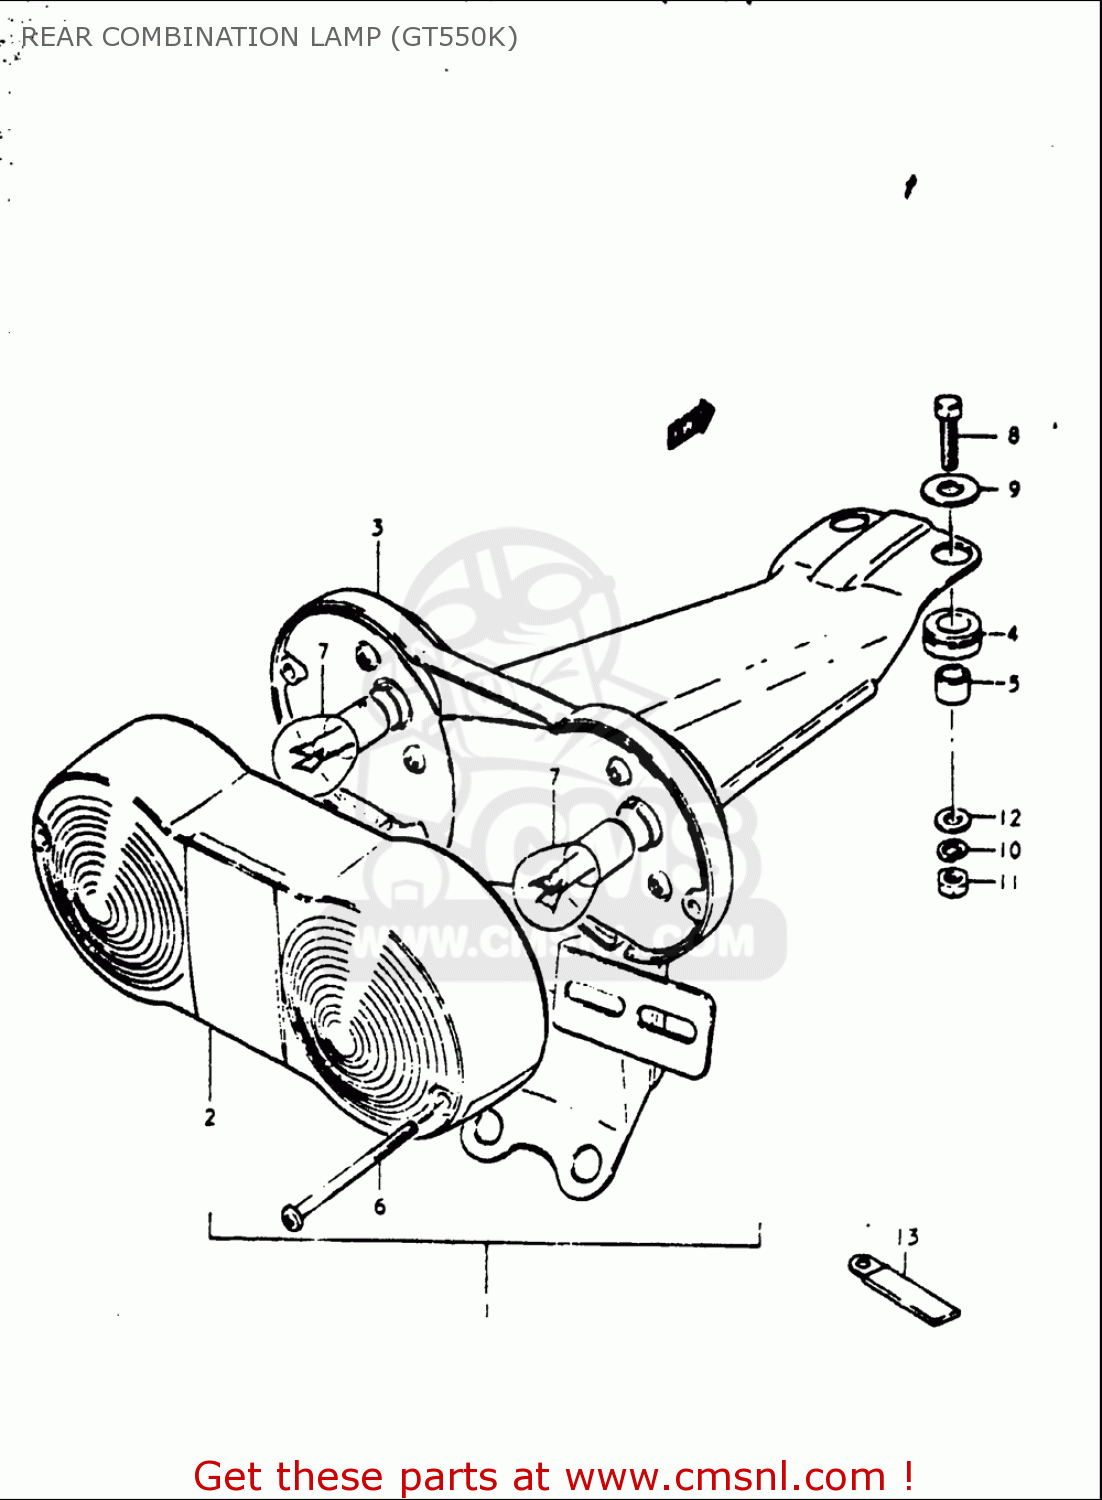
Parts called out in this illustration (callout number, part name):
2	LENS,REAR COMBINATION LAMP
4	CUSHION
5	SPACER
6	SCREW
7	BULB(12V23W)
8	BOLT
9	WASHER(6.5X20X1.6)
10	WASHER,LOCK
11	NUT
12	WASHER
13	CLAMP
